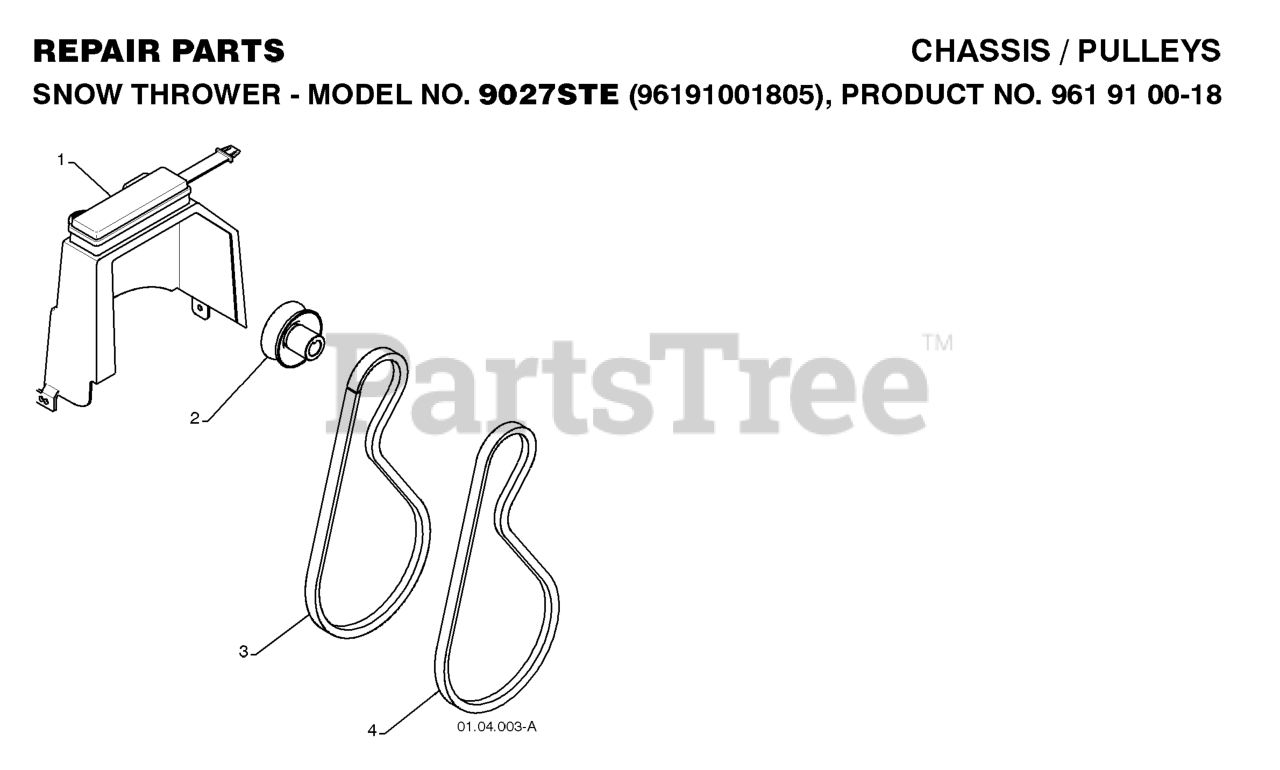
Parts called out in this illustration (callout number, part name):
1	COVER.ASM.BELT/STORAGE
2	PULLEY, ENGINE IMPELLER DRIVE
3	V-BELT TRACTION 34.25
4	BELT.V.IMPELLER
